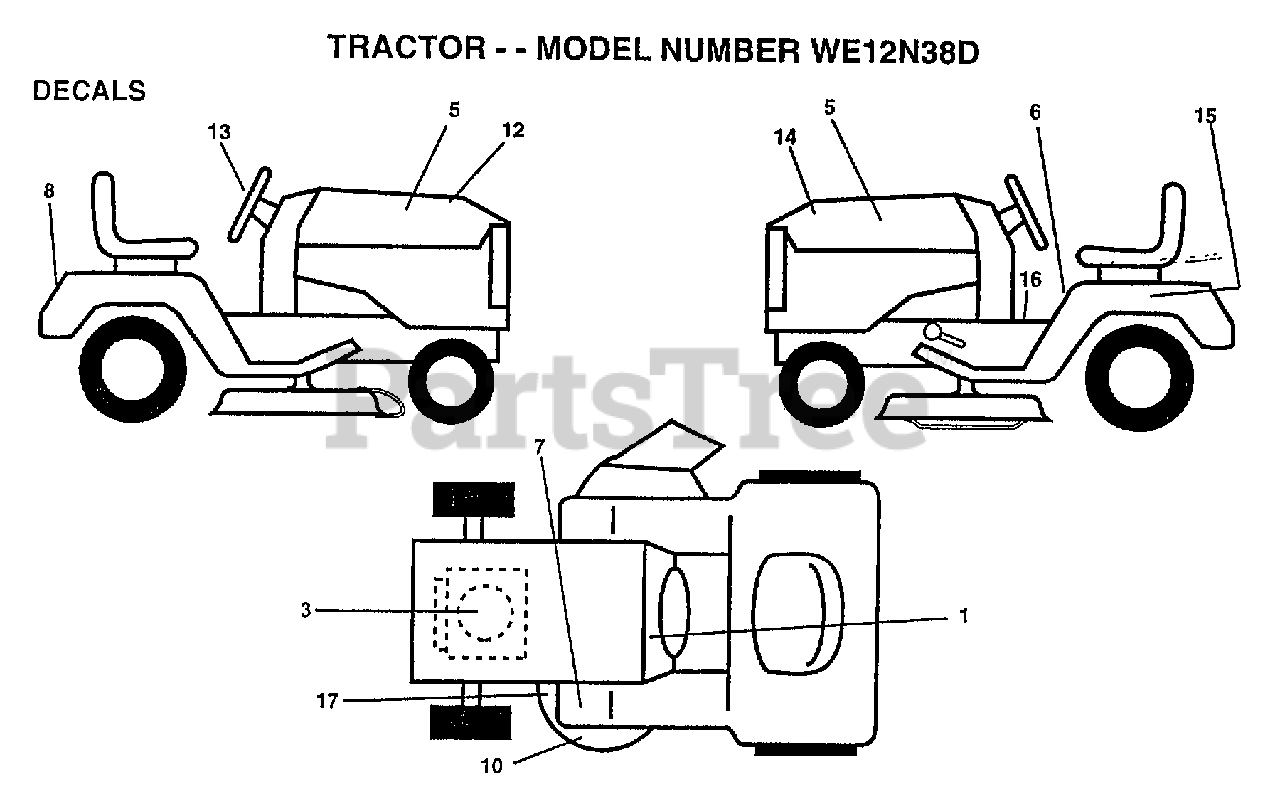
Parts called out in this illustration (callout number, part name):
1	"DECAL-OPER,GEAR D"
3	DECAL, HP ENGINE
5	DECAL PANEL SIDE
6	"DECAL DANGER,FEND"
8	DECAL-FENDER
12	"DECAL HOOD, RH"
13	DECAL INS STEER W
14	"DECAL HOOD, LH"
15	DECAL.BATRY.3-3908
16	DECAL BRAK PARK
17	DECAL
